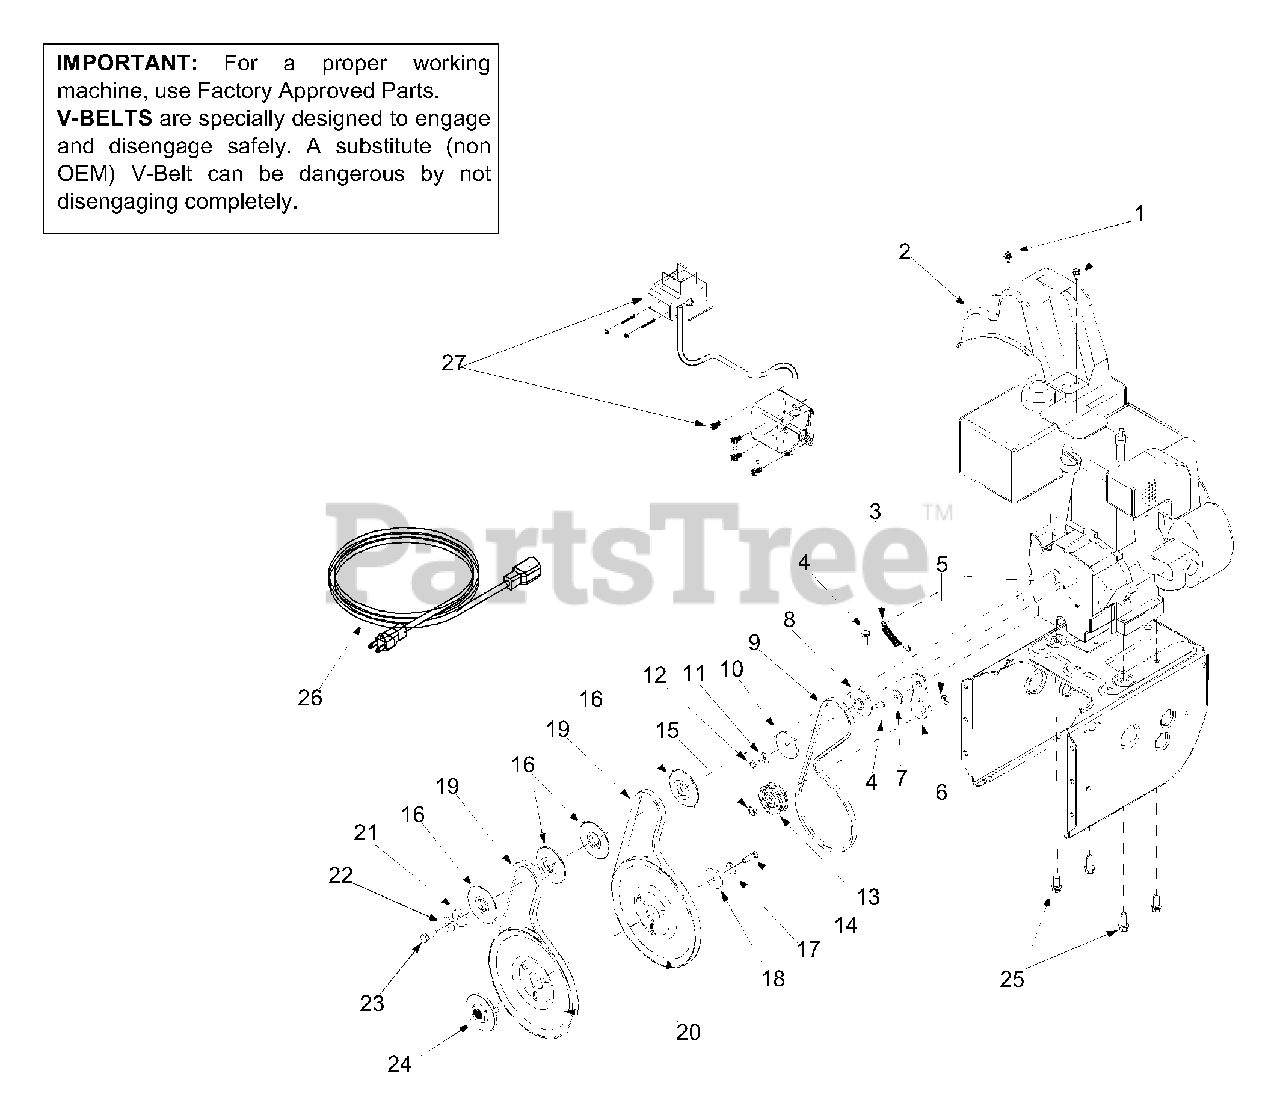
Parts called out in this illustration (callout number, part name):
1	Hex Washer Screw 1/4-20 x .50
2	Belt Cover
3	Extension Spring
4	Hex Screw 5/16-24 x .75
5	Hex Cap Screw 3/8-16 x 1.25
8	Pulley Half
9	V-Belt
10	Pulley Half
11	Bell Washer
12	Hex Cap Screw 1/4-28 x .50
13	Flat Idler
14	Lock Hex Cap Screw 5/16-24
15	Lock Jam Nut 3/8-16
16	Pulley Half
17	Bell Washer
18	Flat Washer
19	Belt
20	Auger Pulley
21	Flat Washer 3/8 x 1.25 OD
22	Bell Washer
23	Hex Cap Screw 3/8-24
24	Adapter Pulley
25	Hex Screw 3/8-16 x 1.0
26	Extension Cord
27	Electric Start
